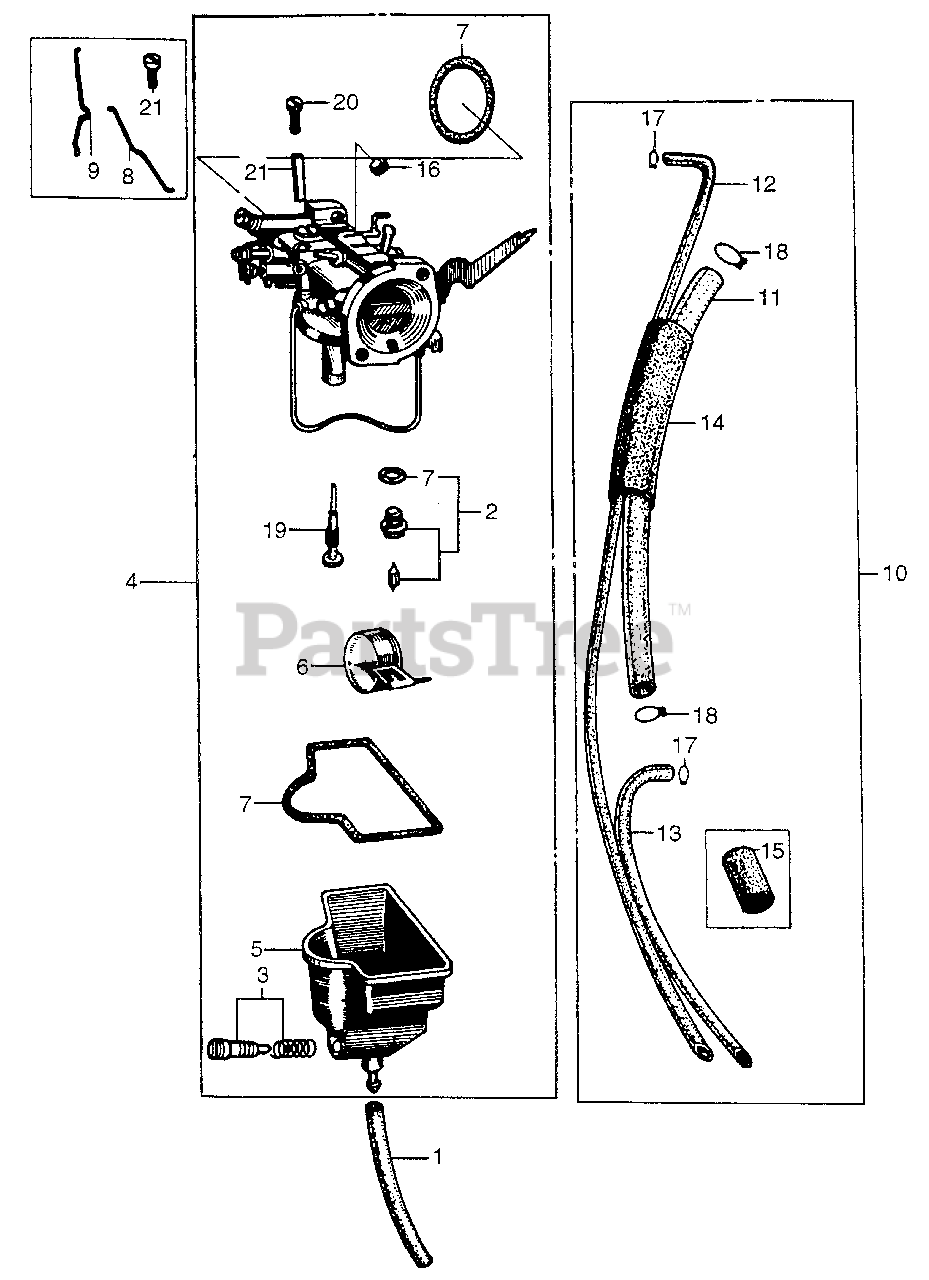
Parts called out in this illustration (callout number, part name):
1	TUBE, CARBURETOR DRAIN (NOT AVAILABLE)
2	VALVE SET, FLOAT
3	SCREW SET, DRAIN (NOT AVAILABLE)
4	CARBURETOR ASSY. (NOT AVAILABLE)
5	CUP, FLOAT (NOT AVAILABLE)
6	FLOAT SET (N/A: USE P/N 16013-812-004) (ALT. PNO: 16013-812-004)
7	GASKET SET (NOT AVAILABLE)
8	ROD, GOVERNOR
9	ROD, CHOKE (NOT AVAILABLE)
10	TUBE ASSY., FUEL (NOT AVAILABLE)
11	TUBE, FUEL (NOT AVAILABLE)
11	TUBE, FUEL
11	BULK HOSE, FUEL (4.5X3000) (4.5X143)
12	TUBE, VALVE BREATHER (NOT AVAILABLE)
13	TUBE, CARBURETOR OVERFLOW (NOT AVAILABLE)
14	RUBBER A, SUPPORTER
14	RUBBER, SUPPORTER
15	RUBBER B, SUPPORTER
16	NUT, HEX. (5MM)
18	CLIP, TUBE (4.5)
19	JET, MAIN (#55) (NOT AVAILABLE)
21	JET, PILOT (#35)
